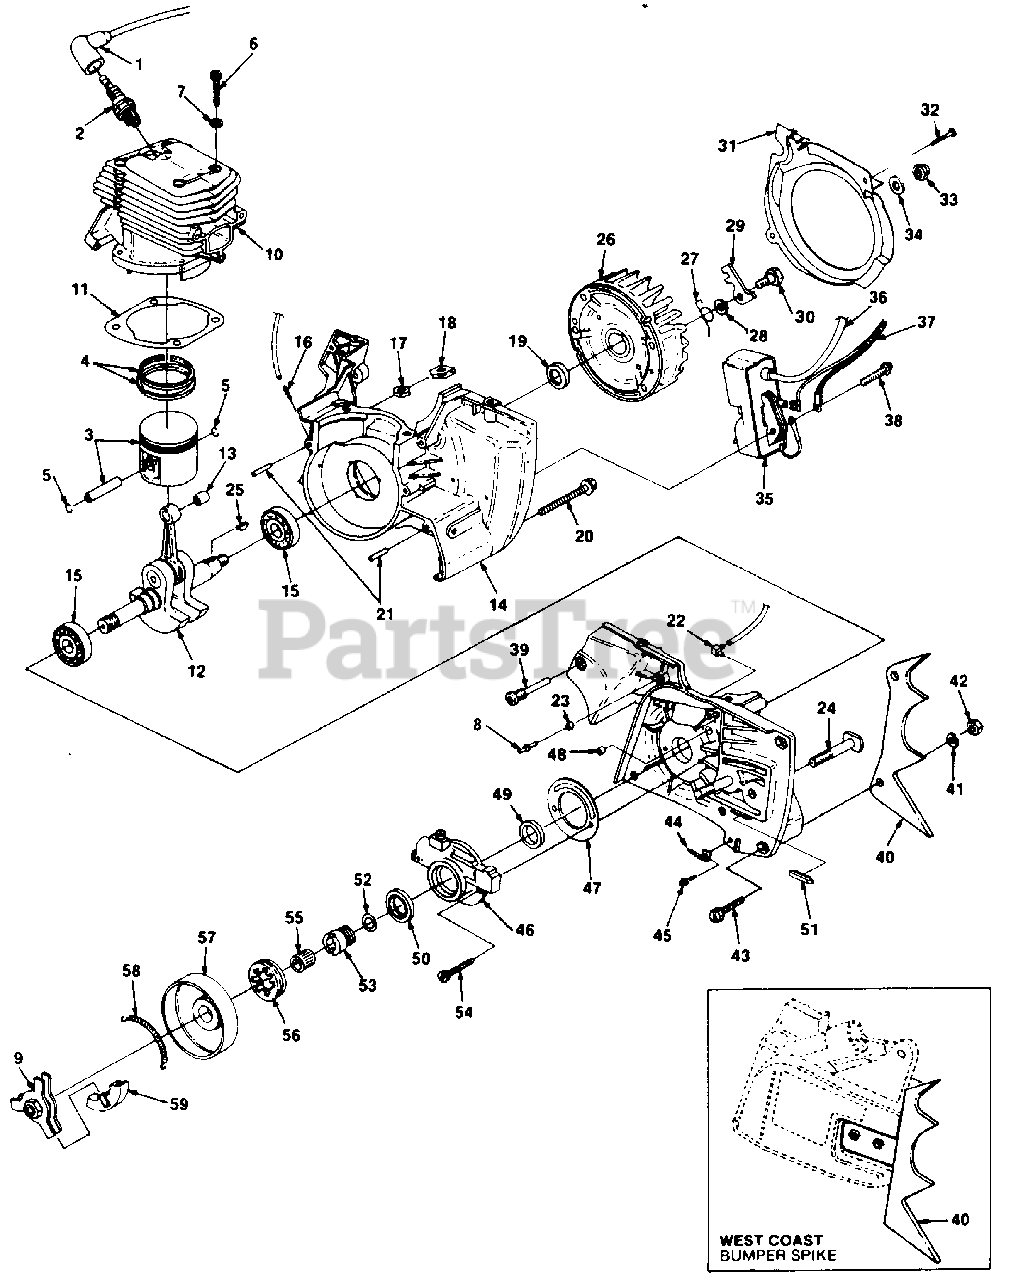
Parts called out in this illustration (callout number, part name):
1	TERMINAL- Spark plug
2	SPARK PLUG (CJ6Y)
3	PISTON & PIN ASSEMBLY
4	PISTON RING
5	RING- Retaining
6	SCREW- Cap socket (10-24 x 1 1/8")
7	WASHER- Conical
8	PIN- Shoulder dowel
9	SPIDER- Clutch
10	CYLINDER
11	GASKET- Cylinder
12	CRANKSHAFT
13	BEARING
14	CRANKCASE ASSEMBLY
15	BEARING- Ball
16	FITTING- Tube
17	NUT- Lock (10-24)
18	NUT- Retainer
19	SEAL
20	SCREW- Hex sems (10-24 x 2")
21	PIN- Dowel
22	FITTING- Tube
23	BUSHING
24	BOLT- Guide bar
25	KEY- Woodruft
27	SPRING- Starter finger
28	WASHER- Lock (#2)
29	STARTER PAWL
30	SCREW- Shoulder
31	SCROLL- Air guide
32	SCREW- Pan hd. (6-32 x .375)
33	NUT- Lock hex (3/8-24)
34	WASHER- Flat
35	MODULE- Ignition
36	LEAD- Ignition
37	LEAD- Ground
38	SCREW- (10-24 x 1")
39	PIN- Isolator
40	BUMPER SPIKE
41	WASHER- Lock (#12)
42	NUT- Hex (#12-24)
43	SCREW- Hex (12-24 x 5/8")
44	CHAIN STOP
45	SCREW- Pan hd. (8-32 x 5/8")
46	OIL PUMP
49	SEAL
50	SEAL- Felt
51	GUIDE- Chain
52	WASHER-Thrust
53	WORM & BEARING
54	SCREW- Soc. cap (1/4 20 x 5/8")
55	BEARING- Needle
56	SPROCKET- 7T x 3/8 Pitch
57	DRUM- Clutch
58	SPRING- Clutch
59	SHOE- Clutch
